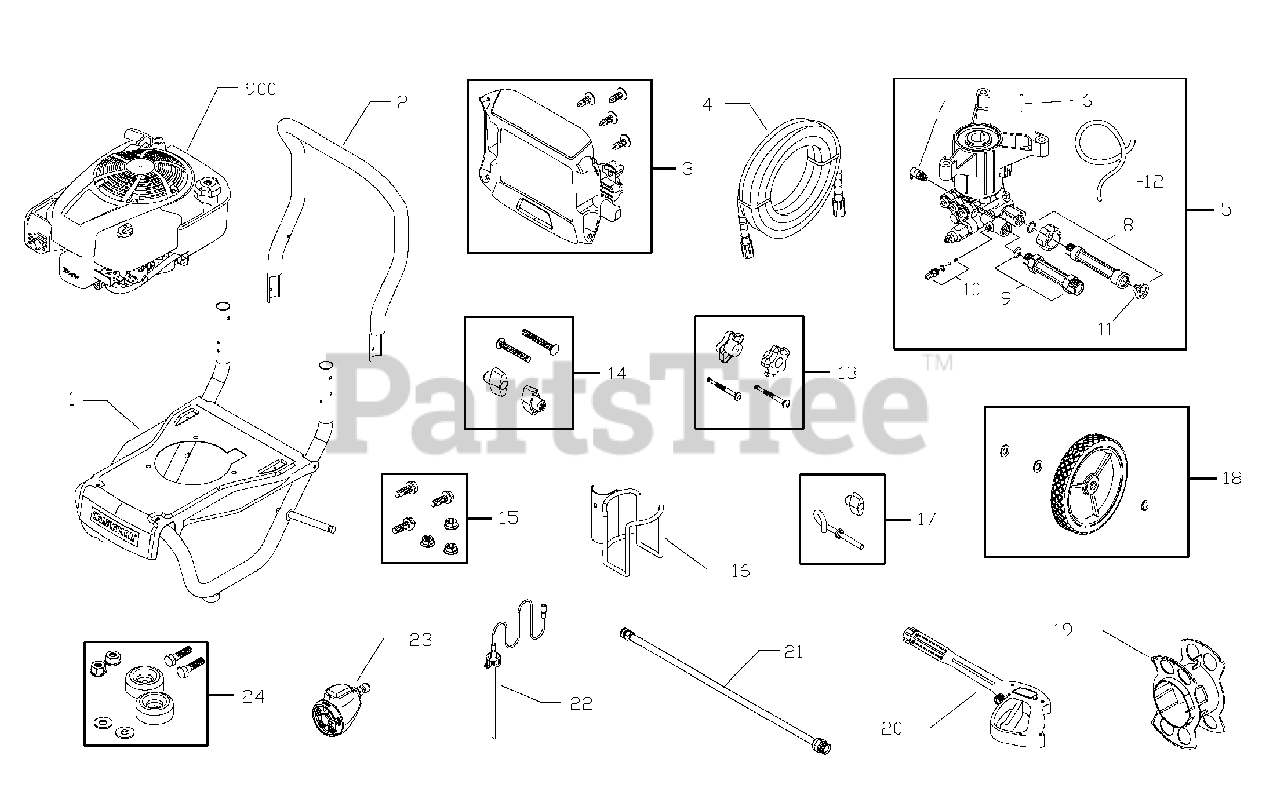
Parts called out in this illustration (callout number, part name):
2	HANDLE
4	HOSE
5	PUMP
7	VALVE, Thermal Relief
8	KIT, Water Inlet
10	KIT, Chemical Injection
11	FILTER, Garden Hose
12	HOSE, Chemical
15	KIT, Hardware Pump Mounting
20	GUN
21	EXTENSION, QC
23	NOZZLE, QC
24	KIT, Vibration Mount
900	*ENGINE
